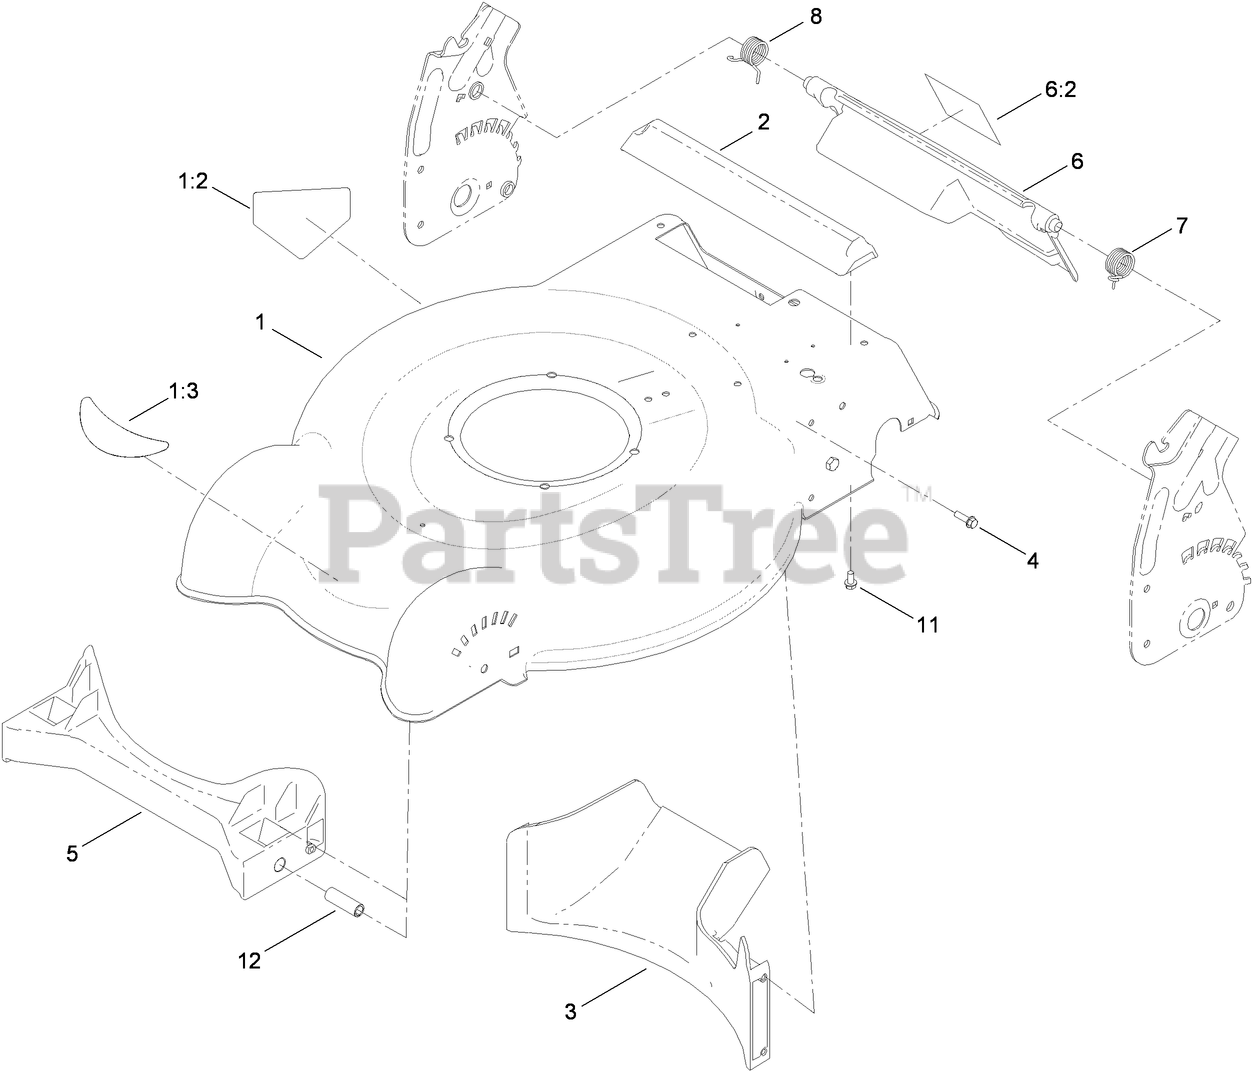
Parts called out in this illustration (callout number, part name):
1	HOUSING ASM
1:2	DECAL-DANGER
1:3	DECAL-DECK
2	CHUTE-REAR
3	BAFFLE-REAR
4	SCREW-HWH
5	BAFFLE-FRONT, RWD (CE)
6	REAR DEFLECTOR ASM
6:2	DECAL-WARNING
7	SPRING-TORSION, LH
8	SPRING-TORSION, RH
11	SCREW-PLASTITE
12	SPACER-BAFFLE, FRONT
